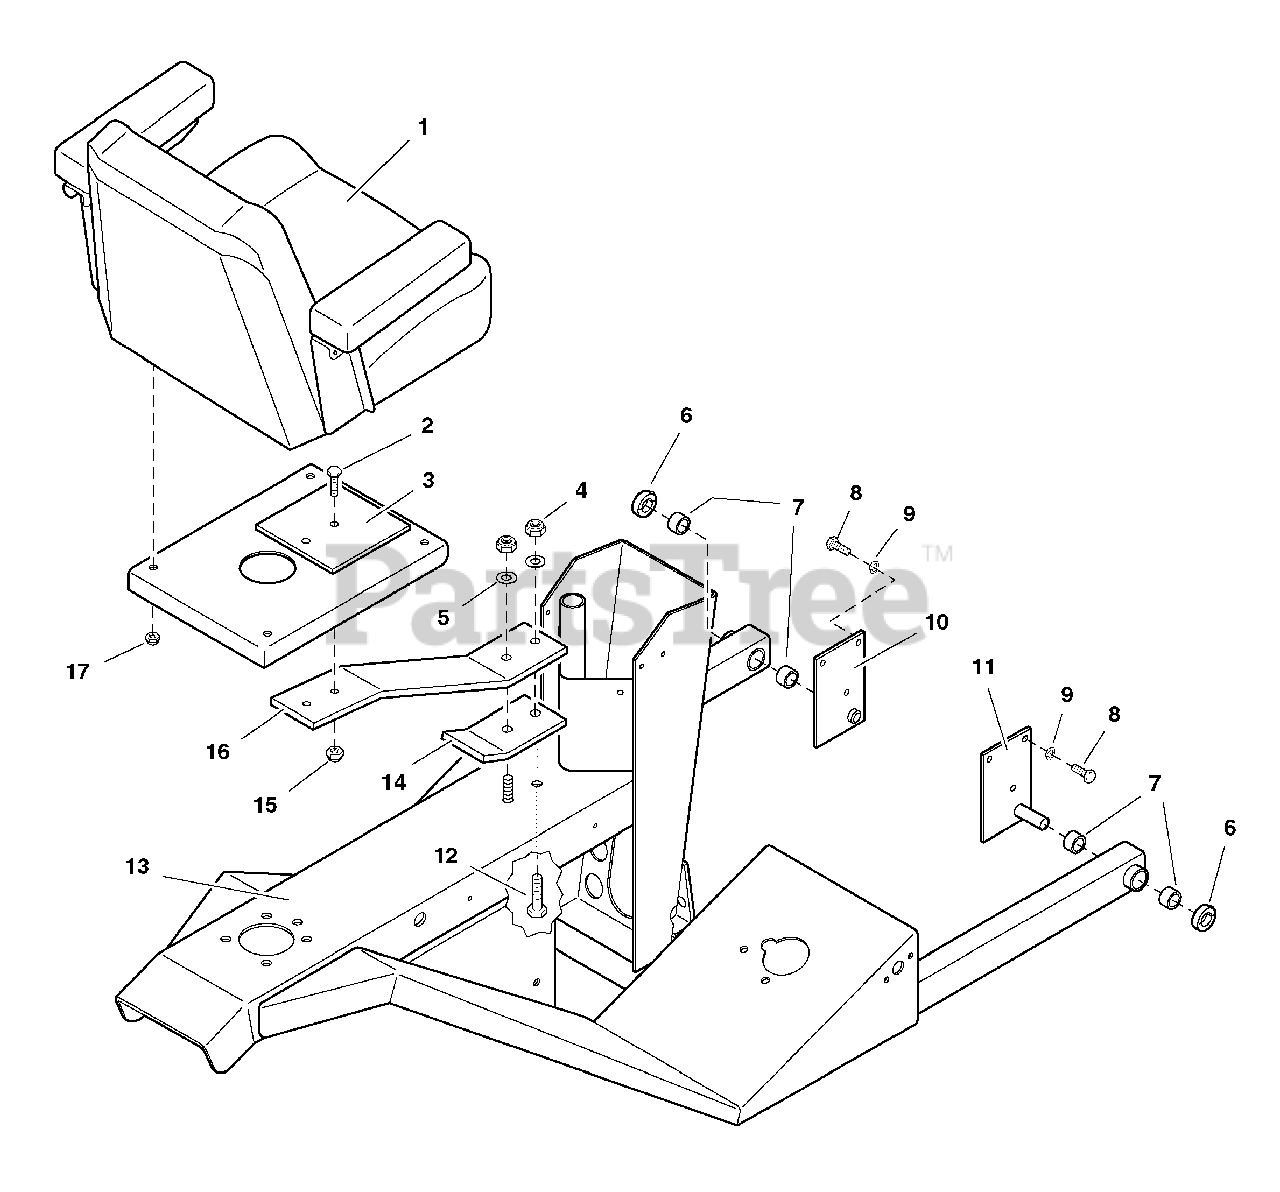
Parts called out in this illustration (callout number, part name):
1	SEAT, Gray, Derby (complete)
2	CAPSCREW, Hex Hd, 3/8-16 x 1-1/4
3	PLATE, Seat Mount
4	NUT, Hex, Nylon Lock, 7/16-20
5	WASHER, 7/16
6	COLLAR, Split, 3/4
7	BUSHING, Plastic
8	CAPSCREW, Hex Hd, 5/16-18 x 1
9	WASHER, Lock, 5/16
10	PIVOT BRACKET-LH
11	PIVOT BRACKET-RH
12	CAPSCREW, Hex Hd, 7/16-20 x 1-3/4
13	TRAILER FRAME
14	SUPPORT, Seat Spring
15	NUT, Hex, Nylon Lock, 3/8-16
17	NUT, Hex, Nylon Lock, 5/16-18
